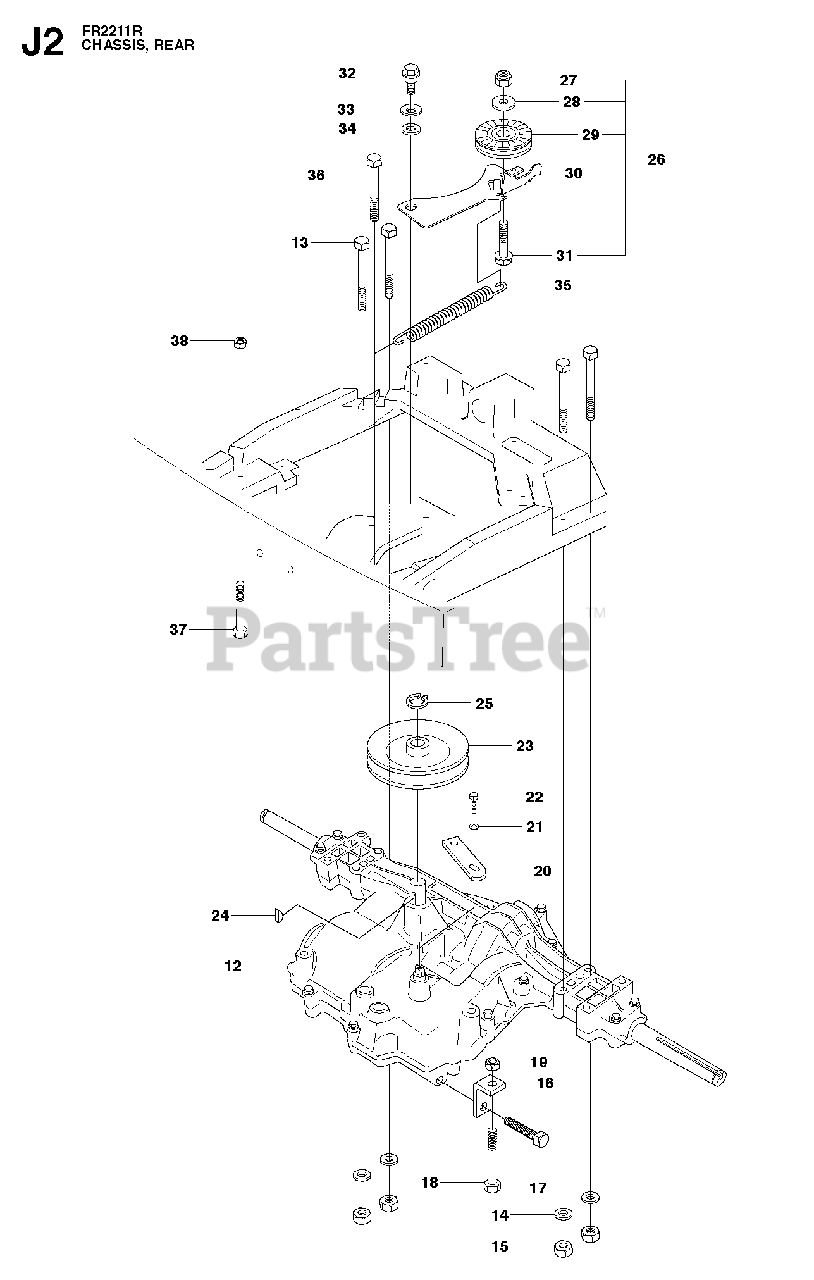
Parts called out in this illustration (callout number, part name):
14	WASHER BRB 8.4X17
15	NUT
16	WIRE BRACKET
19	NUT
21	WASHER
25	RETAINING RING SGA 16
27	LOCKNUT M8
28	SPACER
29	PULLEY
31	SCREW
33	SPRINGWASHER
34	WASHER - M12
38	NUT
